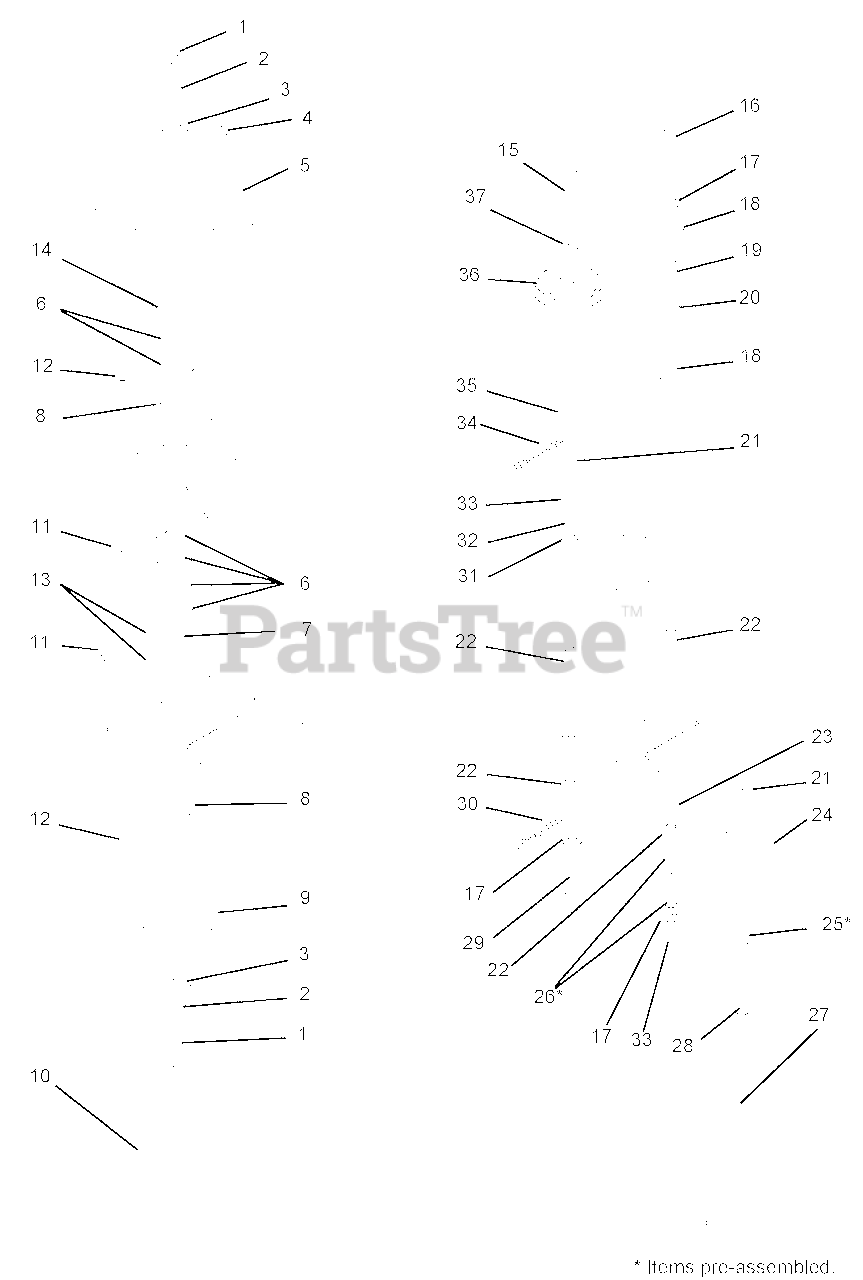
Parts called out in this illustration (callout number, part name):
1	Bolt, Hex .25-20 x .75 Grade 5
2	Washer-Locking .25 x .062 Regular
3	Washer-Flat-Steel .344 x 1.125 x .135
4	Nut-Spin Lock-Flange .312-18
5	Pulley-V 9.0 x 1.25
6	Washer-Flat-Steel .755 x 1.25 x .125
7	Shaft, Zoom Snow Throw
8	Bearing, 2 Bolt Flange-.75 ID
9	Sheave, Blower- 4.25 Diameter
10	V-Belt 4L-Section 56.45 x .516
11	Bolt-Round Head Square Neck .31-18 x .75 Grade 5
12	Nut-Locking-Top-Flange .31-18
13	Key-Square .187 x .50 x .187 Hardened
14	Hub Assembly
15	Bolt-Hex .38-16 x 2.25 Grade 5
16	Bolt, Hex .50-13 x 7.00
17	Washer-Flat-Steel .531 x 1.06 x .095
18	Bushing, Nylon, Flange .762 x 1.0 x .580 x 1.48
19	Bushing, Steel .560 x .745 x 2.04 Steel
20	Weldment, Idler
21	Nut-Locking-Jam-Center .375-16
22	Bushing-Sleeve .500 x .750 x 1.560
23	Bushing, .516 x 1.0 x 1.05
24	Idler Flanged 3.50
25	Weldment, Idler
26	Bushing, Flanged 0.75 x 0.875 x .625 x 1.125
27	V-Belt, 112.3
28	Bolt-Round Head Square Neck .38-16 x 1.75 Grade 5
29	Bolt-Hex .50-13 x 1.50 Grade 5
30	Spring, Extension
31	Washer-Locking .50 x .125
32	Nut-Hex .50-13
33	Nut-Locking-Center-Jam .500-13
34	Spring, Extension
35	Nut-Locking-Jam-Center .375-16
36	Pulley, Idler 4.00
37	Washer, Flat Steel .406 x .812 x .065
